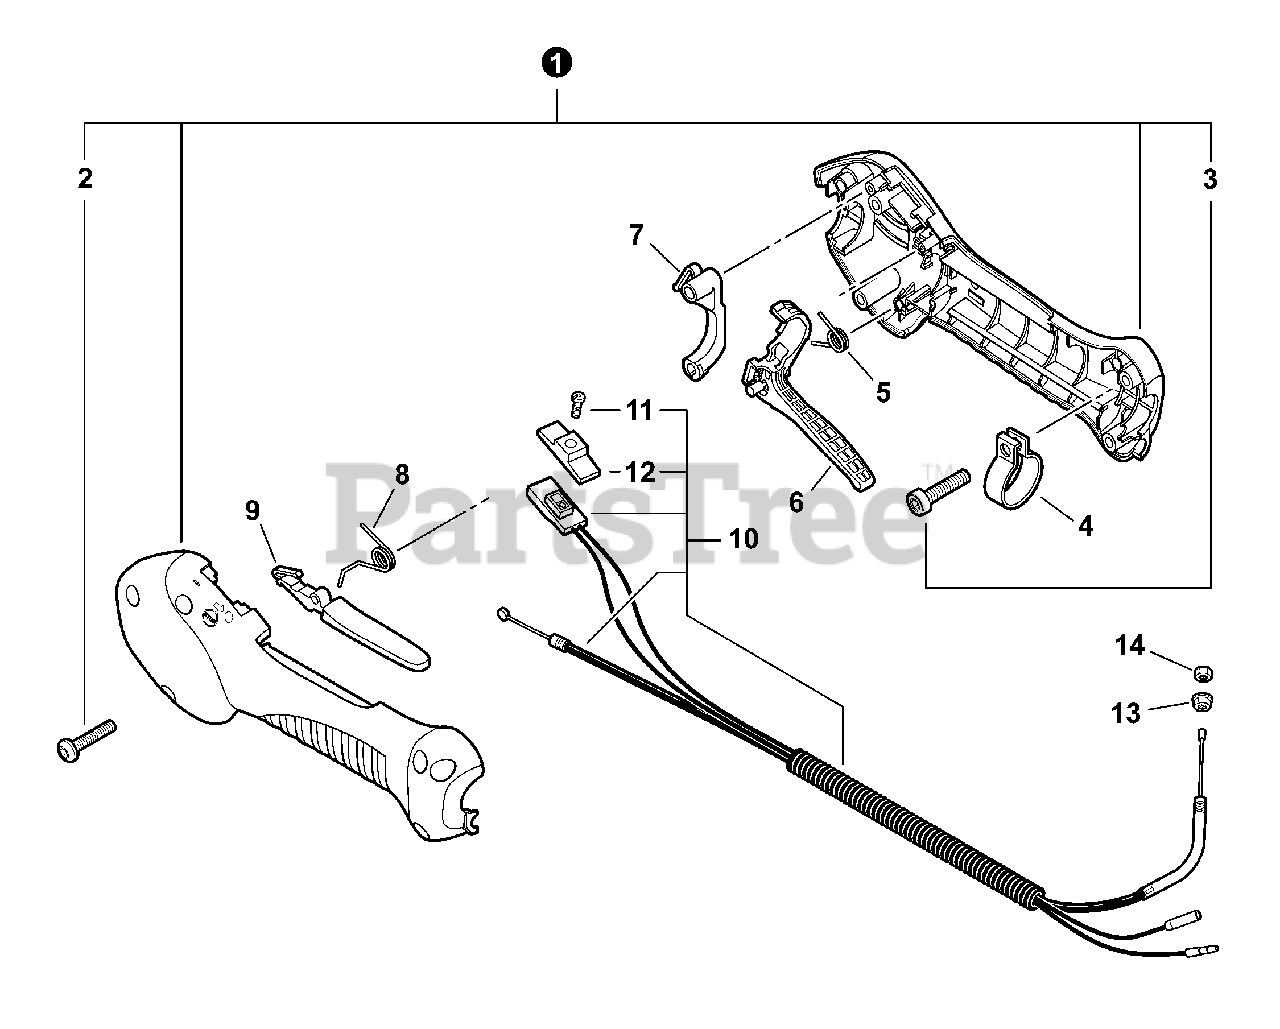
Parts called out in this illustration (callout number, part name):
1	CONTROL HANDLE ASSY
2	SCREW - 4×20 -- TAPPING
3	SCREW - 5×20
5	SPRING, TRIGGER
6	TRIGGER, THROTTLE
7	LOCKOUT, TRIGGER
8	SPRING, LEVER RETURN
9	LEVER, THROTTLE LOCKOUT
10	CONTROL CABLE ASSY
11	SCREW - 3×10
12	KNOB, SWITCH - ORANGE
13	NUT - 6 -- FLANGE
